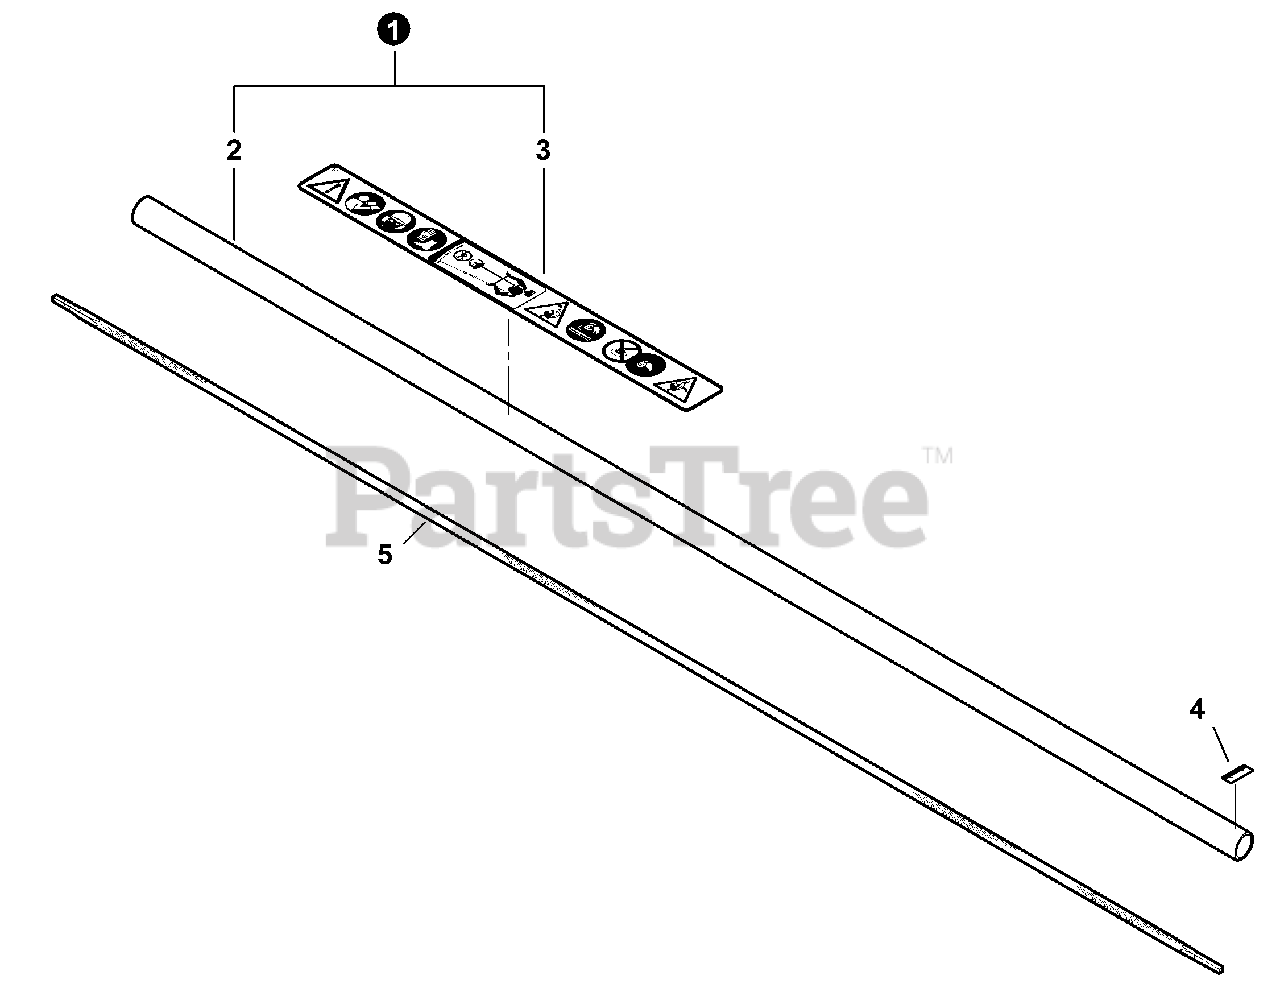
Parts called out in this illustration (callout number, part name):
1	MAIN PIPE ASSY
2	MAIN PIPE ASSY 25×1500
3	LABEL, CAUTION - ISO
4	LABEL - ALIGNMENT
5	DRIVESHAFT - FLEXIBLE L= 1522
